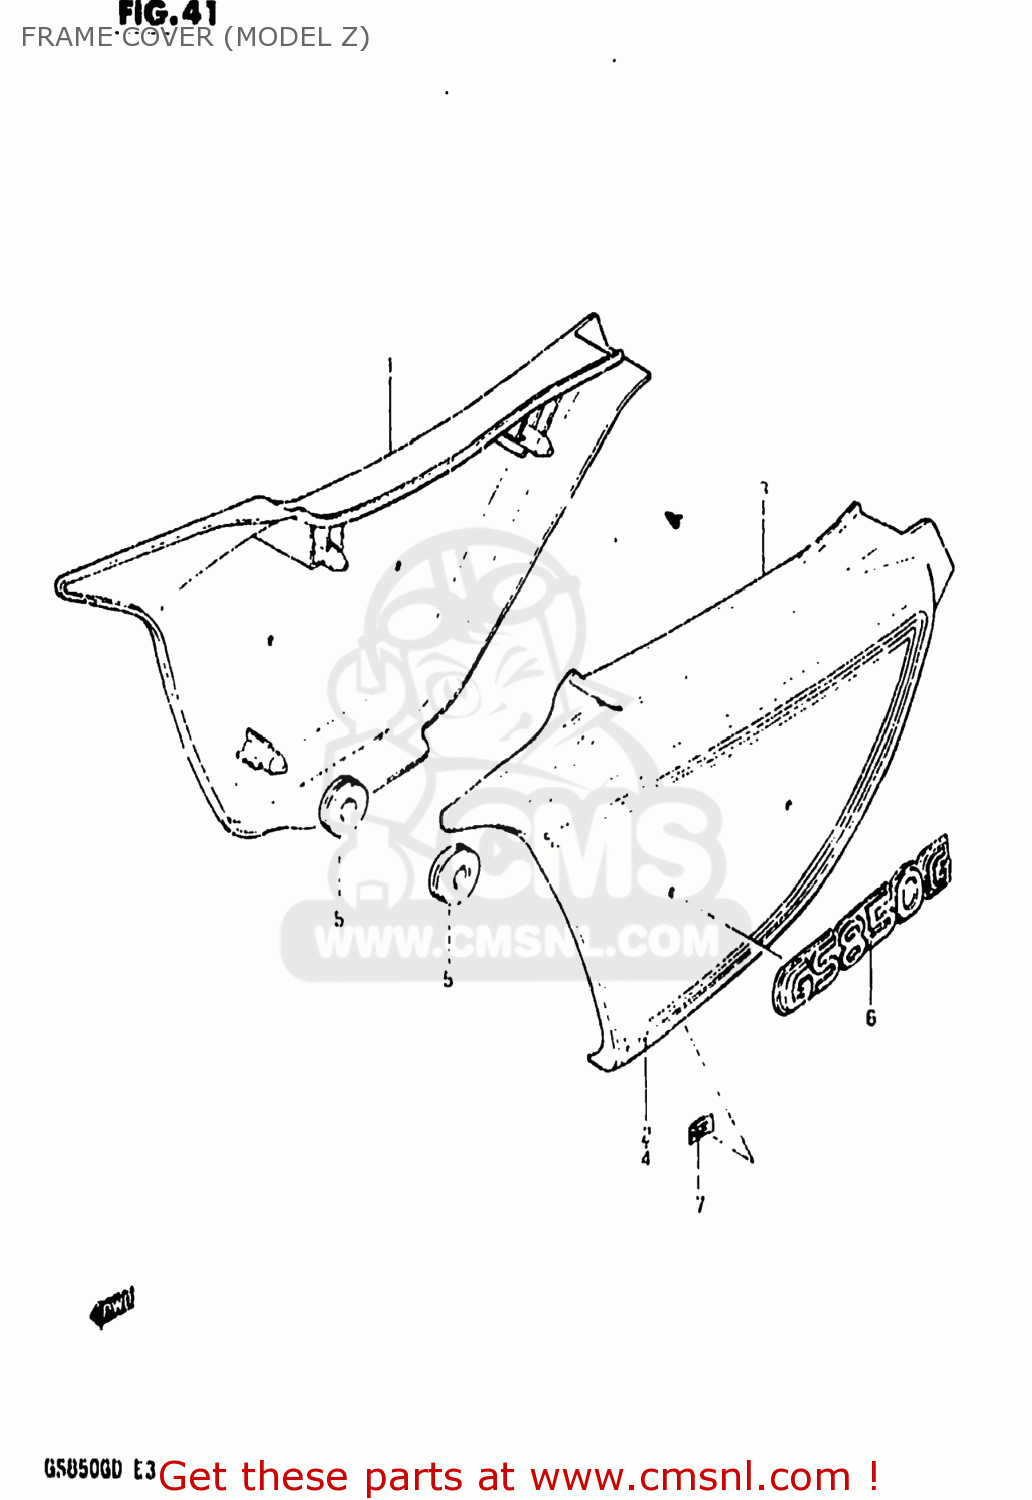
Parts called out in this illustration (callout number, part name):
1	COVER,FRAME,RIGHT
2	TAPE SET,FRAME COVER
3	COVER,FRAME,LEFT
4	TAPE SET,FRAME COVER
5	CUSHION
6	EMBLEM
7	NUT
